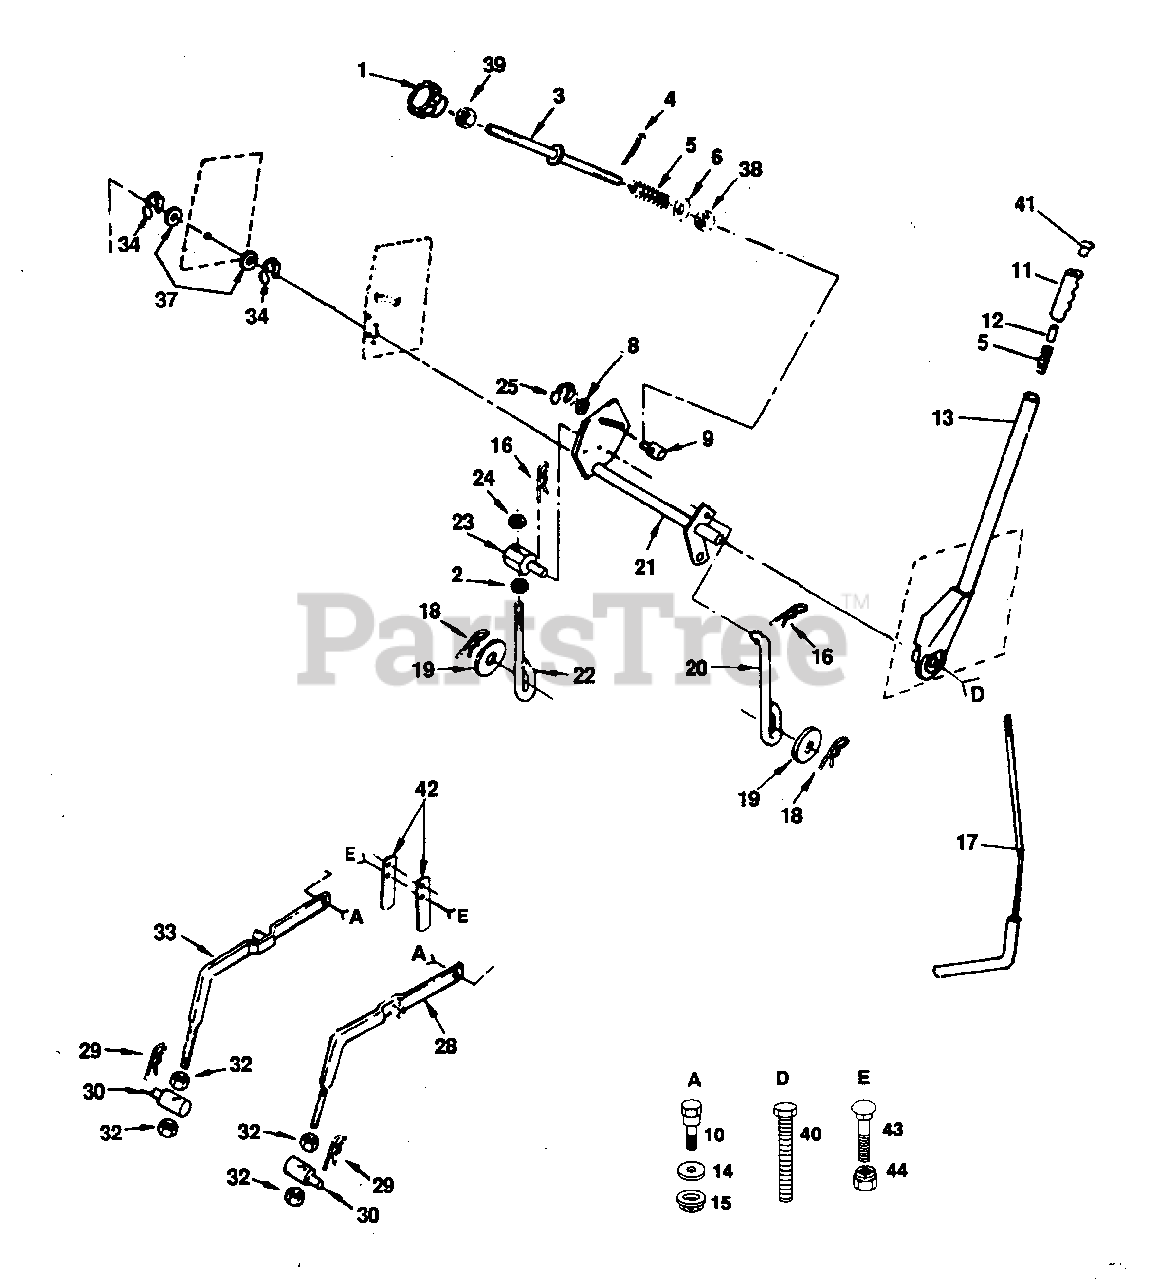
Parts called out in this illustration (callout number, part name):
1	Knob, Depth Adjustment
2	Nut, Hex 3/8-16
3	Rod, Adjust, Lift
4	Pin, Cotter 3/32 x 1/2
5	Spring
6	Washer 13/32 x 5/8 x 16 Ga.
8	Washer 15/32 x 3/4 x 16 Ga.
10	Bolt, Shoulder 3/8-16
11	Grip Handle
12	Plunger, Lever
13	Lever, Lift
14	Spring Washer
15	Center Lock Flange Nut 3/8 x 16
16	Retainer, Spring
18	Retainer Spring
19	Washer, 17/32 x 15/16 x 16 Ga.
22	Link Lift, Adjust
23	Trunnion, Lift
24	Nut, Lock 7/16-14
28	Arm, Suspension R.H.
29	Retainer, Spring
30	Trunnion, Lift, Lower
32	Nut, Hex Fin. 1/2- 13
33	Arm, Suspension, L.H.
34	E - Ring, Truarc
37	Washer 29/32 x 1-1/4 x 16 Ga.
39	Nut, Hex Jam 3/8 x 16 UNC
40	Bolt, Hex 3/8-16 x 1-1/2
41	Button, Plunger
42	Upstop, Mower
43	Bolt, Carriage 3/8-16 x 1
44	Nut, Crownlock 3/8-16
